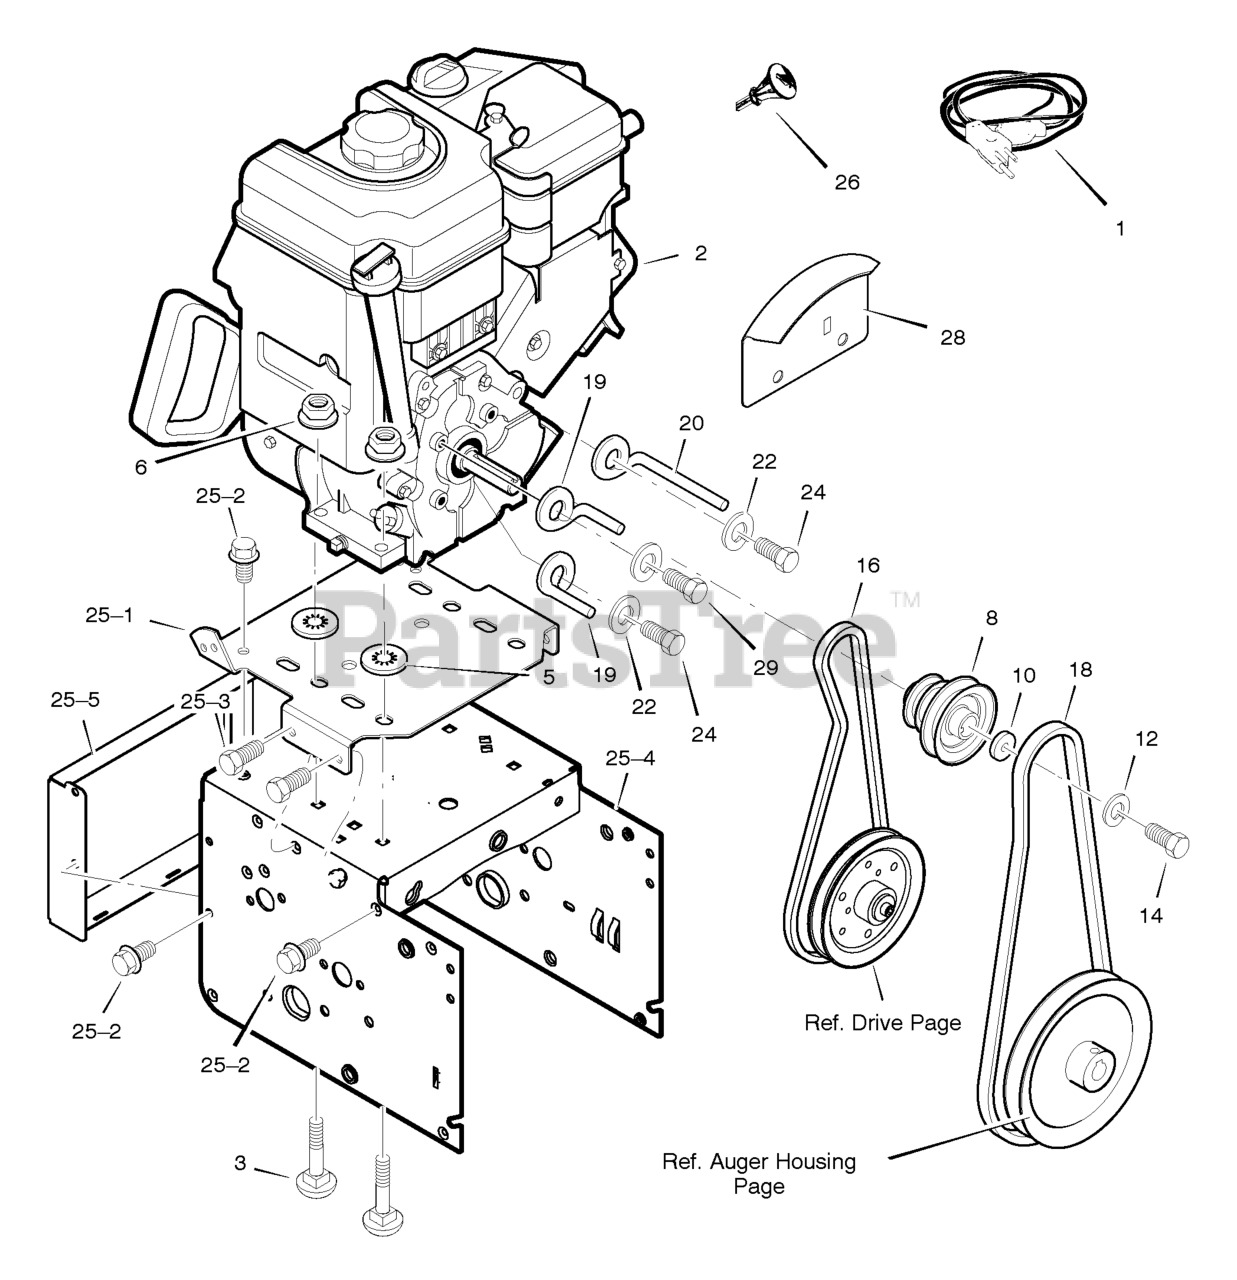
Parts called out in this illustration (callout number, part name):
1	CORD, STARTER
2	ENGINE
3	BOLT, CARRIAGE 5/16-18
5	RETAINER, PUSH
6	NUT, HEX 5/16-18
8	PULLEY, ENGINE
10	WASHER
12	WASHER .38ID
14	SCREW, 3/8-24 x 1.00
16	BELT, HYDRO DRIVE
18	BELT, AUGER V 4L
19	GUIDE, BELT
20	GUIDE, BELT
22	WASHER, SPTLK .31X.58X.08
24	SCREW, 5/16-24 x 0.75
25	FRAME ASSEMBLY
25-1	PLATE, ENGINE MOUNT
25-2	SCREW, TAP 1/4-20 X .63
25-3	SCREW, TAP 5/16-18 X .50
25-4	FRAME, MOTOR BOX
25-5	PANEL, BACK - HYDRO
26	KEY, ENGINE
28	SHIELD, ENGINE
